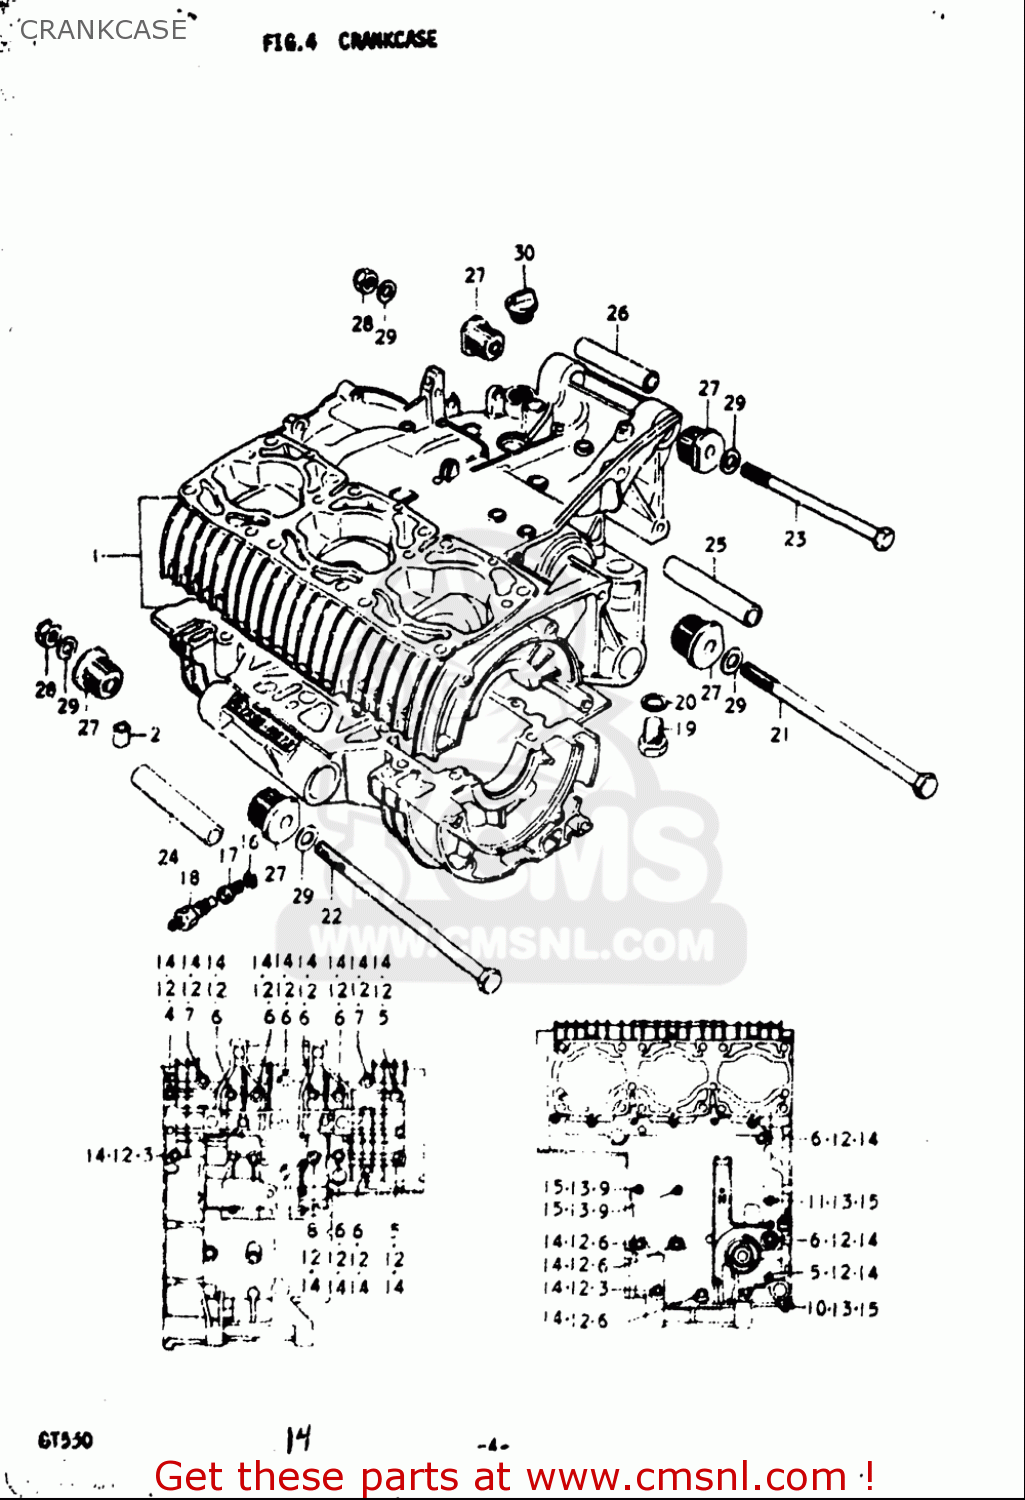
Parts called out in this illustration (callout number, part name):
2	PIN
3	BOLT(8X105)
4	BOLT
5	BOLT
6	BOLT
7	BOLT
8	BOLT
9	BOLT
10	BOLT
11	BOLT
12	WASHER
13	WASHER
14	WASHER,LOCK
15	WASHER,LOCK
16	GASKET(8.2X14X1) (NAS)
18	CHECK VALVE,SRIS
19	PLUG
20	GASKET(14X19.2X2) (NAS)
23	BOLT(10X185)
27	BUSH
28	NUT
29	WASHER
30	PLUG SET
